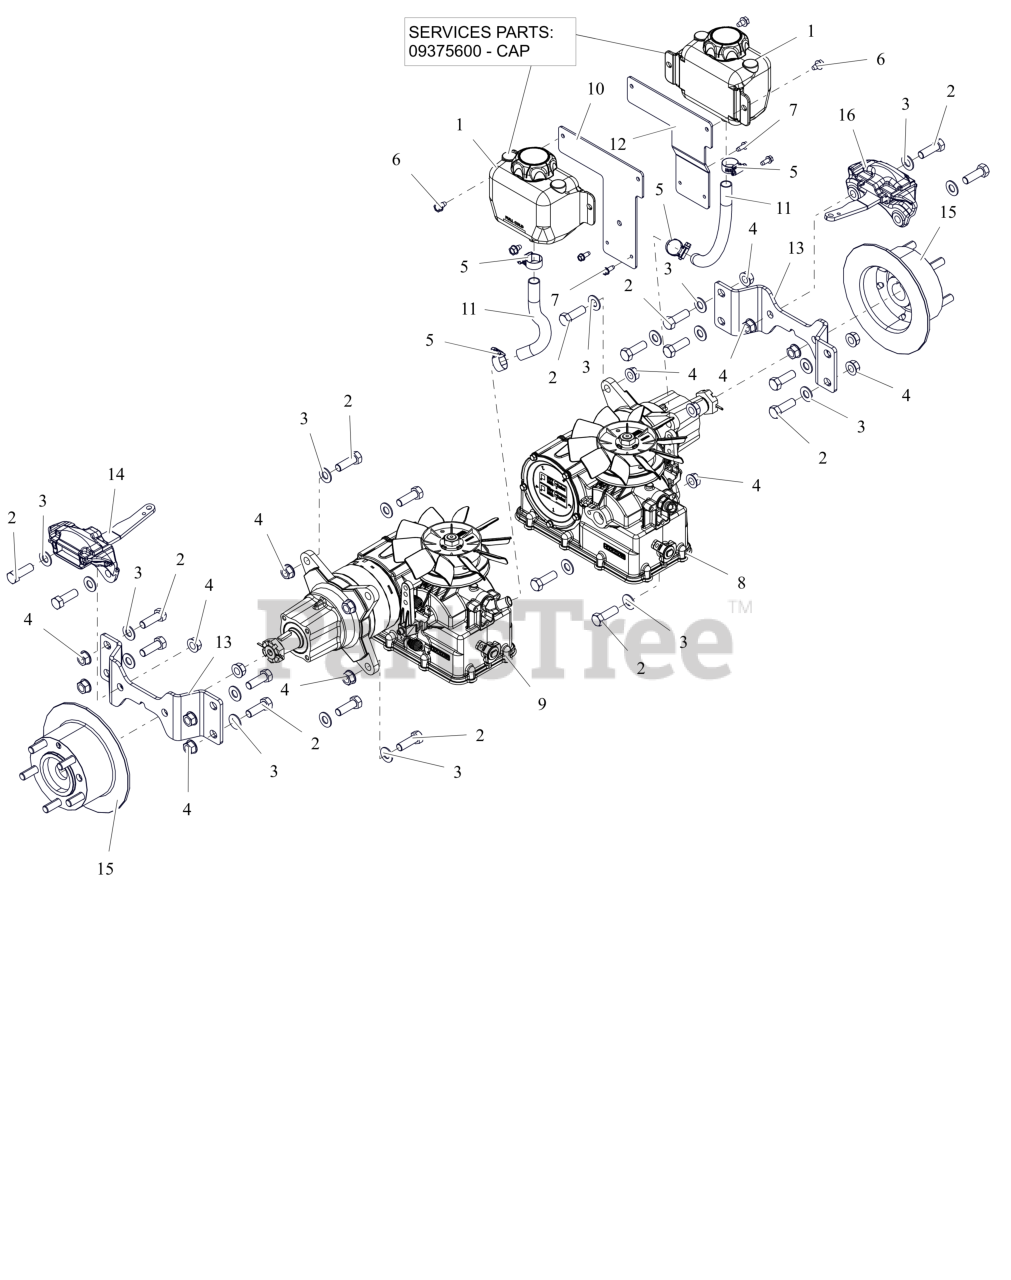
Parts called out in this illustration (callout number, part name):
1	TANK, TRANSAXLE OVERFLOW - 1 QT
1	CAP
2	BLT, HEX 0.5-13X1.5 GR8 ZCC
3	WSHR, FLT .557X1.040X.102 ZCC
4	NUT, FLG-CTR LK .500-13 GG ZCC
5	CLAMP,.88 DIA. HOSE
6	SCR,TAP .312-18X.50 HWH TR ZCC
7	SCR,TAP .25-20X.625 HWH ZCC
8	TRANSAXLE, LH PARKER HTG13/30
9	TRANSAXLE, RH PARKER HTG13/130
10	BRKT, RH OVERFLOW TANK MTG (BLACK)
11	HOSE, PT600 TRANSAXLE OVERFLOW
12	BRKT, LH OVERFLOW TANK MTG (BLACK)
13	BRKT, CALIPER MTG (RED)
14	BRAKE, CALIPER RH
15	ROTOR, BRAKE W/STUDS
16	BRAKE, CALIPER LH
